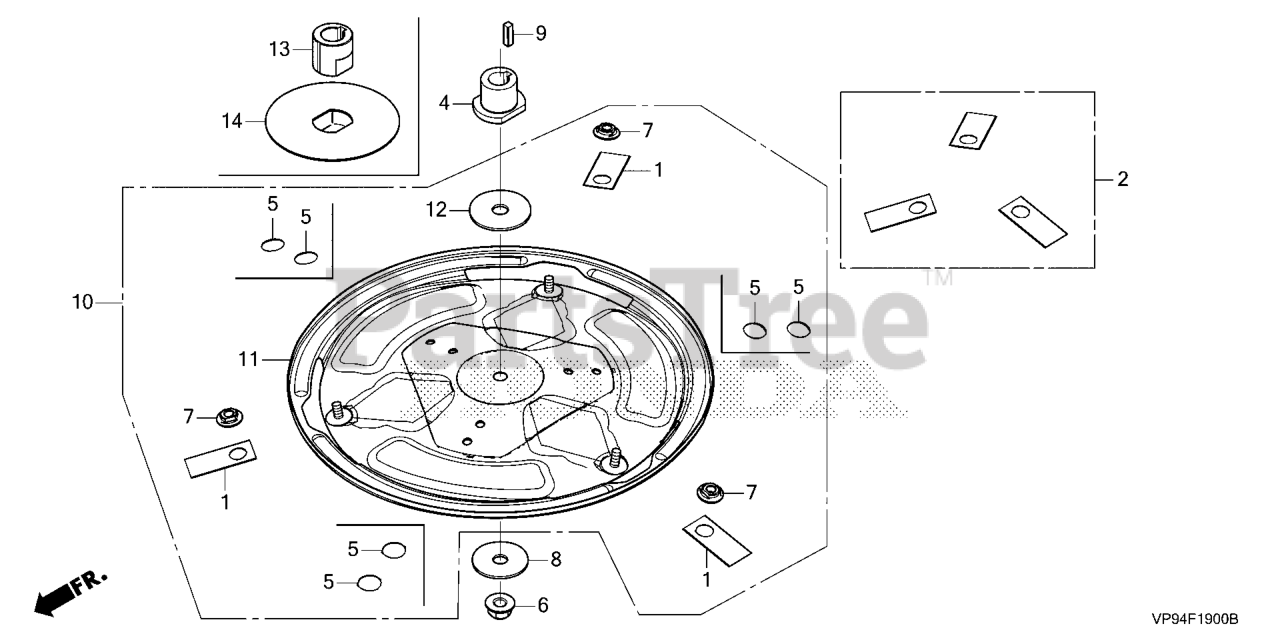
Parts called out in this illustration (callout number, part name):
1	BLADE, ROTARY
2	BLADE SET, ROTARY
3	DISK, BLADE (SEAL)
5	SEAL, BLADE DISK
6	NUT, SELF-LOCK (8MM)
7	NUT, BLADE (5MM)
8	WASHER (8.5X32X1.5)
9	KEY FLAT (4X4X14)
10	DISK KIT, BLADE
11	DISK, BLADE
12	WASHER (8.5X36X1.5)
13	HOLDER, BLADE DISK
14	COVER, HOLDER
